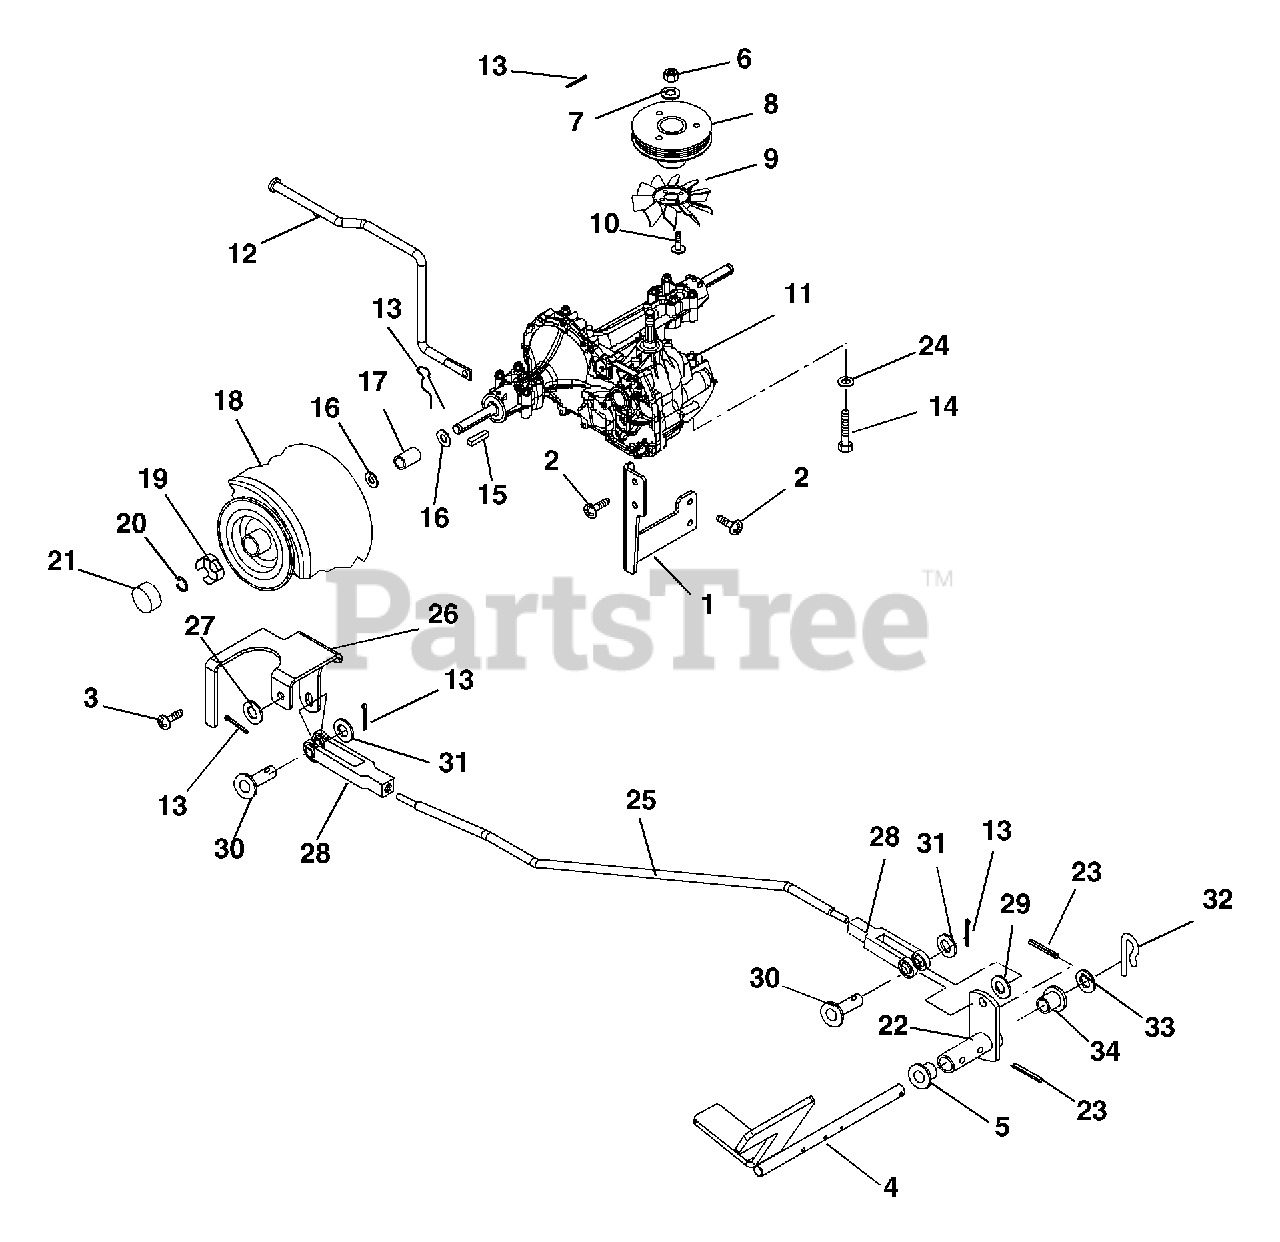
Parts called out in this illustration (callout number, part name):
1	Transmission Support, Rear Engine Rider Hydro
2	Screw, Tapping .38-16 x .75 Hex Washer Head
3	Screw, Tapping .31-18 x .50 Hex Washer Head
4	Weldment, Forward and Reverse Pedal
5	Bushing, Flange .502 x 1 x .75
6	Nut, Jam .50-20 Grade 2
7	Washer, Lock .50 x .125 Reg.
8	Pulley, Transmission
9	Fan, 6 Inch
10	Screw, Tapping 10-24 x .484
11	Transaxle, Hydro
12	Rod, Transmission Disconnect
13	Pin, Hair
14	Bolt, Hex .31-18 x 2.75 Grade 5
15	Key, Square .188 x 2.0 x .188
16	Washer, Flat Steel .755 x 1.375 x .062
17	Spacer, Wheel .75 x 1.00 x 1.25
18	Assembly, Tire and Wheel 16 x 6.5 x 8
18	Tire 16 x 6.50-8 2 Pulley
19	Spindle Cup
20	Ring, Retaining External .75 x .05
21	Hub Cap
22	Weldment, Shift Rod and Hub
23	Pin, Spring Clip
24	Washer, Flat Steel .344 x .688 x 065
25	Rod, Shift Rear Engine Rider Hydro
26	Bracket, Shift Rod
27	Washer, Flat Steel .406 x .812 x .065
28	Yoke .31-24 x 2.250
29	Washer, Flat Steel .390 x .750 x .125
30	Pin, Clevis .31 x .822
31	Washer, Flat Steel .38 x .87 x .179
32	Clip, Spring
33	Washer, Flat Steel .52 x .827 x .062
34	Bushing, Flange .515 x .75 x .745 x 1.00
